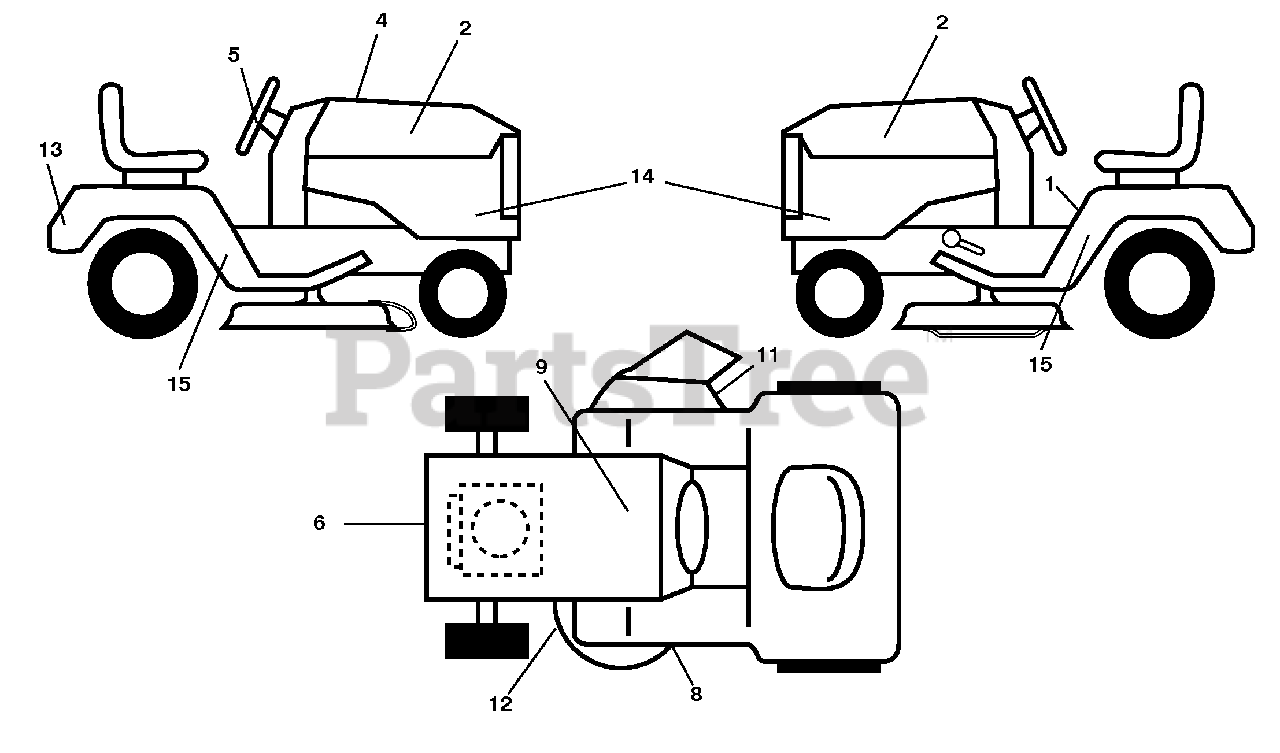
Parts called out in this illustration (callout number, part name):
1	Decal, Operator's
2	Decal, Hood RH/LH
4	Decal, Replacement
5	Decal, Strg Whl
6	Decal, Engine HP
8	Decal, Mower Sch.
9	Decal, Battery Dnge/Poi
11	Decal, Mower Caution
12	Decal, Mower Warning Keep Hand Away
13	Decal, Fender
14	Decal, Panel SD
15	Decal, Fender SD LH/RH
15	Decal, Bypass
15	Pad, Footrest, RH
15	Pad, Footrest, LH
15	Manual, Operator's (Eng & French)
15	Manual, Operator's (Spanish)
15	Manual, Parts
